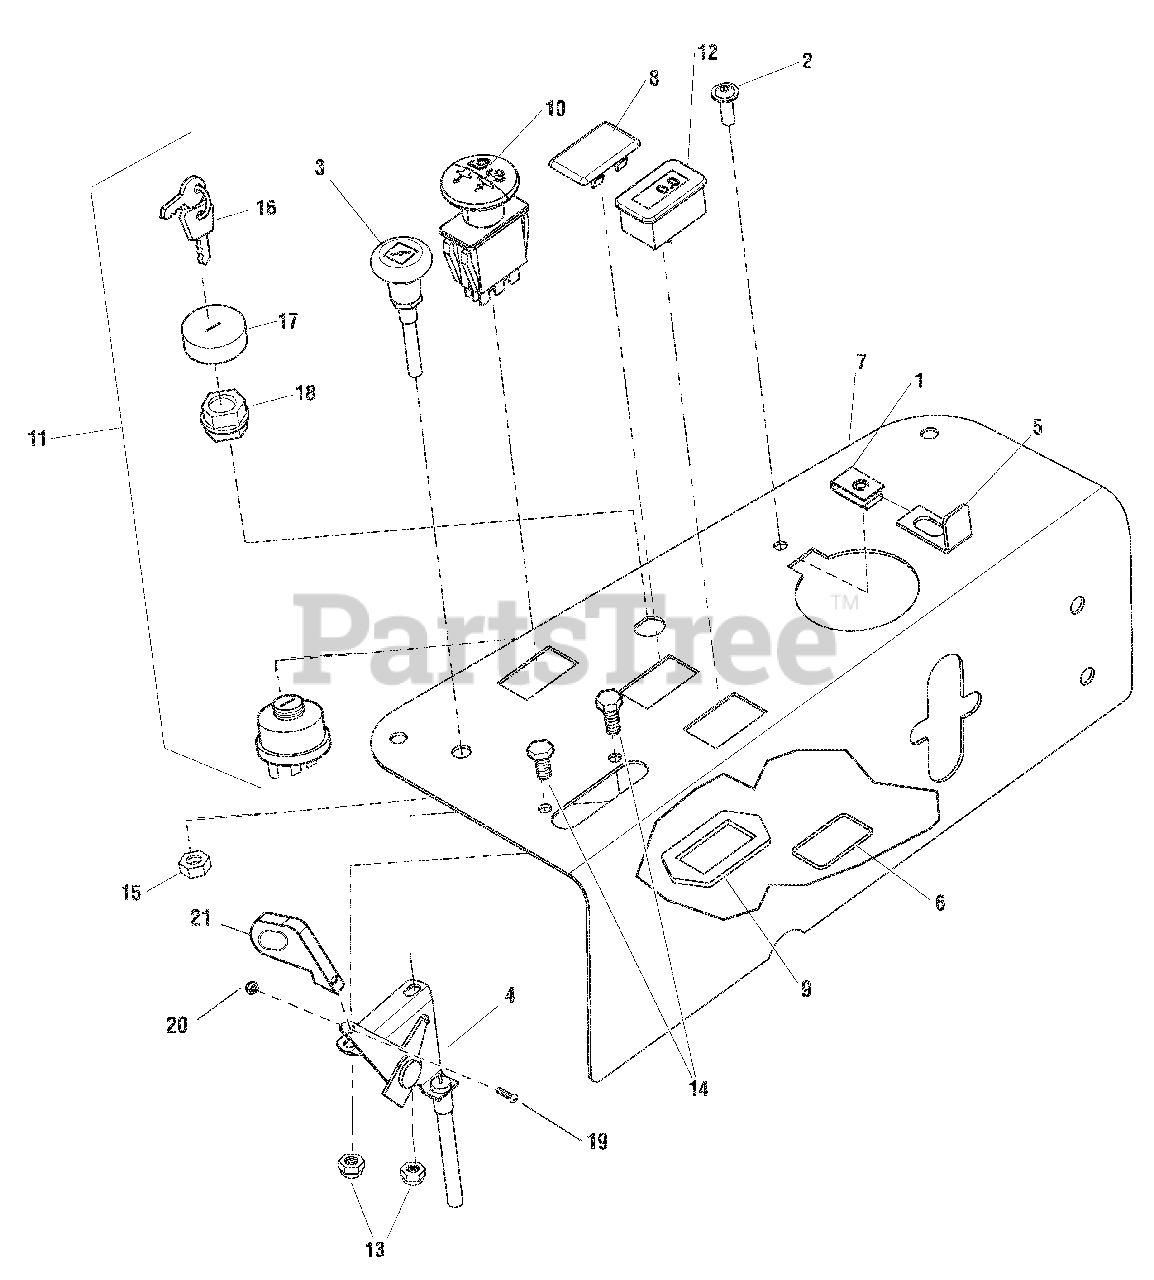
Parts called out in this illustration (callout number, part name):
1	BODY CLIP, 1/4-20 X 1/2" DEEP
2	SCREW, 1/4-20 X 3/4" ALLEN BH
3	CABLE, CHOKE CONTROL, 43.5"
4	CABLE, THROTTLE CONTROL, 36"
5	BRACKET, LOCK
6	O-RING, 7/8" ID X 1/16" W
7	PLATE, CONTROL PANEL
8	PLUG, .820X1.44 HOLE, BLACK PLASTIC
9	RING, SWITCH RETAINER
10	SWITCH, BLADE ENGAGEMENT
11	SWITCH, IGNITION, 6 POST
12	METER, HOUR DIGITAL
13	NUT, 1/4-20 HEX NYLON LOCK
14	BOLT, 1/4-20 X 3/4" GD5 YZ
15	NUT, 3/8-24 HEX
16	KEY, Ignition Molded
17	COVER
18	PLASTIC NUT
19	SCREW, #10-24 X 1" RS
20	NUT, #10-24 HEX NYLON LOCK
21	KNOB, THROTTLE
